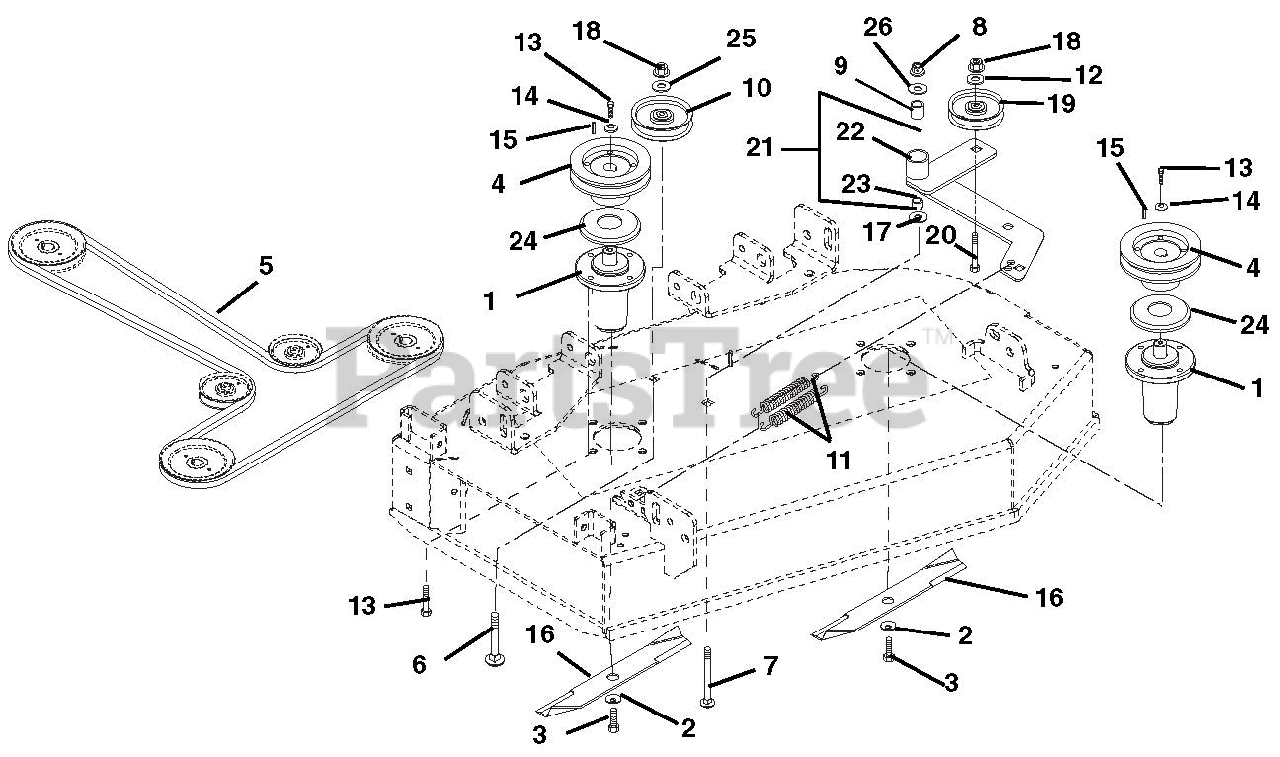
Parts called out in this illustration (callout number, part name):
1	Assembly, Maintenance Free Spindle
2	Washer, Bellville .63 x 1.625 x .14
3	Bolt-Hex .62-18 x 1.75 Grade 8
4	Sheave, 5.00 Spindle (1.00 I.D.)
5	V-Belt, B-Section 49.68 x .62548.80 x .625
6	Bolt, Round Head Square Neck .38-16 x 3.0 Grade 5
7	Bolt, Round Head Square Neck .50-13 x 3.50 Grade 5
8	Nut, Nyloc Flange .50-13
9	Bushing, Spacer .505/.500 x .999/.996 x 2.05/2.03
9	Bearing, Pedestal (991043)
10	Idler-Flat 4.00 x .38 (2.00 W)
11	Spring, Extension
12	Washer, Flat-Steel .375 x 1.125 x .065
13	Bolt, Hex .38-16 x 1.00 EP30
14	Washer, Flat-Steel .406 x 1.50 x .245
15	Key, Square .25 x .25 x 1.00
16	Blade, Mower Hi-Lift
16	Blade, Mulching 50" Mower
17	Washer, Flat Steel .531 x 1.250 x .100
18	Nut, Nyloc Flange 3/8-16
19	Idler, Flat 4.00 x .38 (1.00 W)
20	Bolt, Round Head Square Neck .38-16 x 2.00 Grade 5
21	Assembly, Idler Pivot Arm
22	Weldment, Idler Pivot Arm
23	Bushing, 1.00 x 1.125 x 1.936
24	Slinger, Dust
25	Seal, Idler Bearing
26	Washer, Flat Steel 511 x 1.441 x .125
